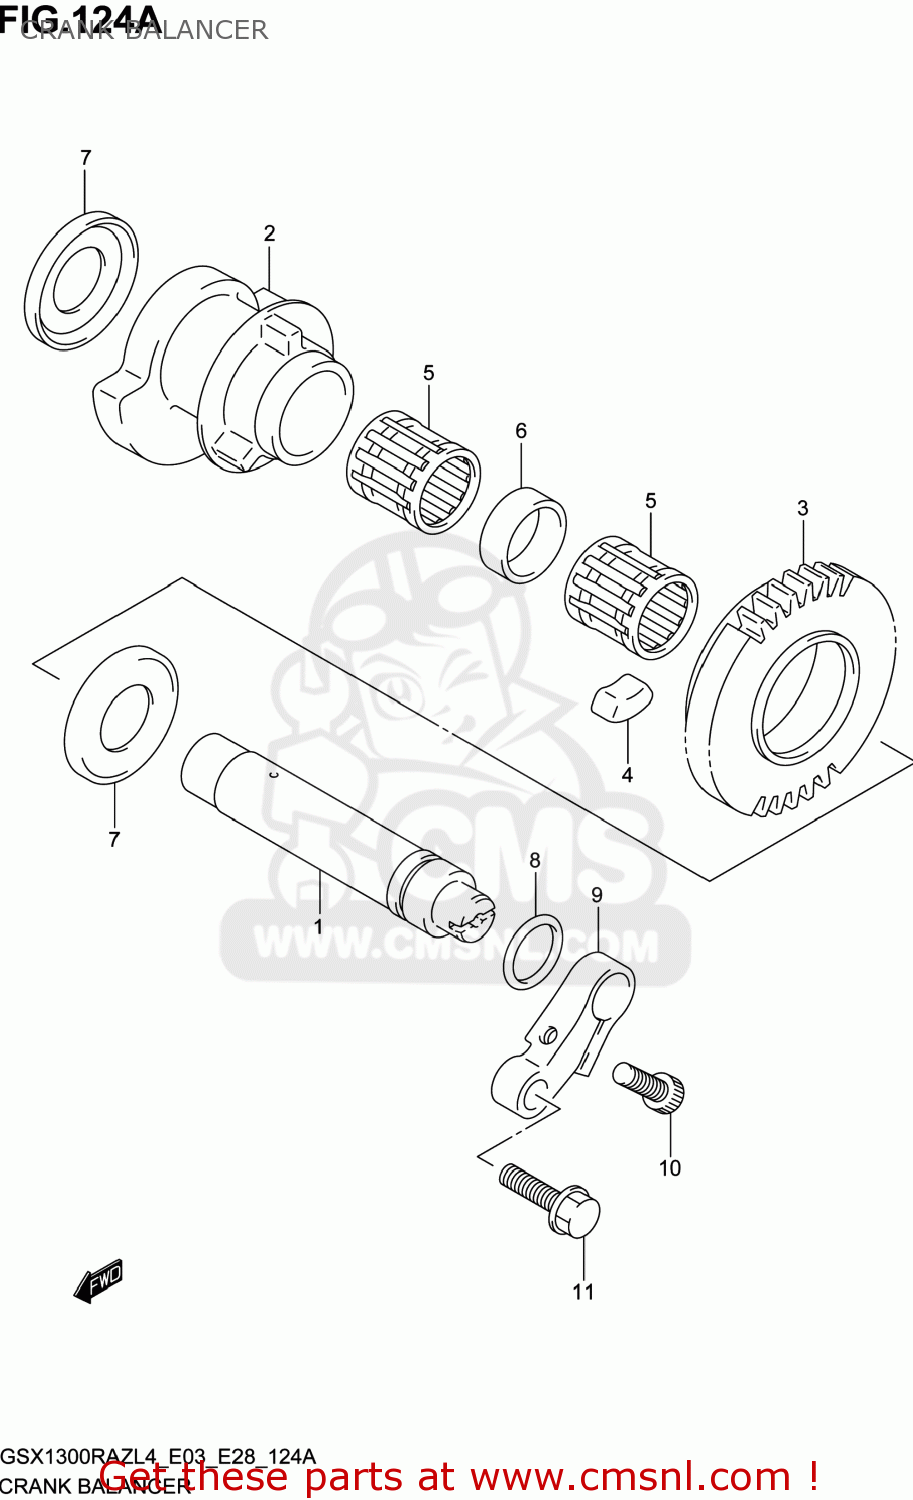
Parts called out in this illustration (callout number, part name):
1	SHAFT,CRANK BALANCER
2	BALANCER,CRANK
3	GEAR,CRANK BALANCER
4	DAMPER,BALANCER GEAR
5	BEARING(19X26X25.2)
6	SPACER(19X26X8.6)
7	WASHER
8	O RING(D:1.9,ID:16.8)
9	ARM,BALANCER SHAFT
10	BOLT
11	BOLT(6X20)
